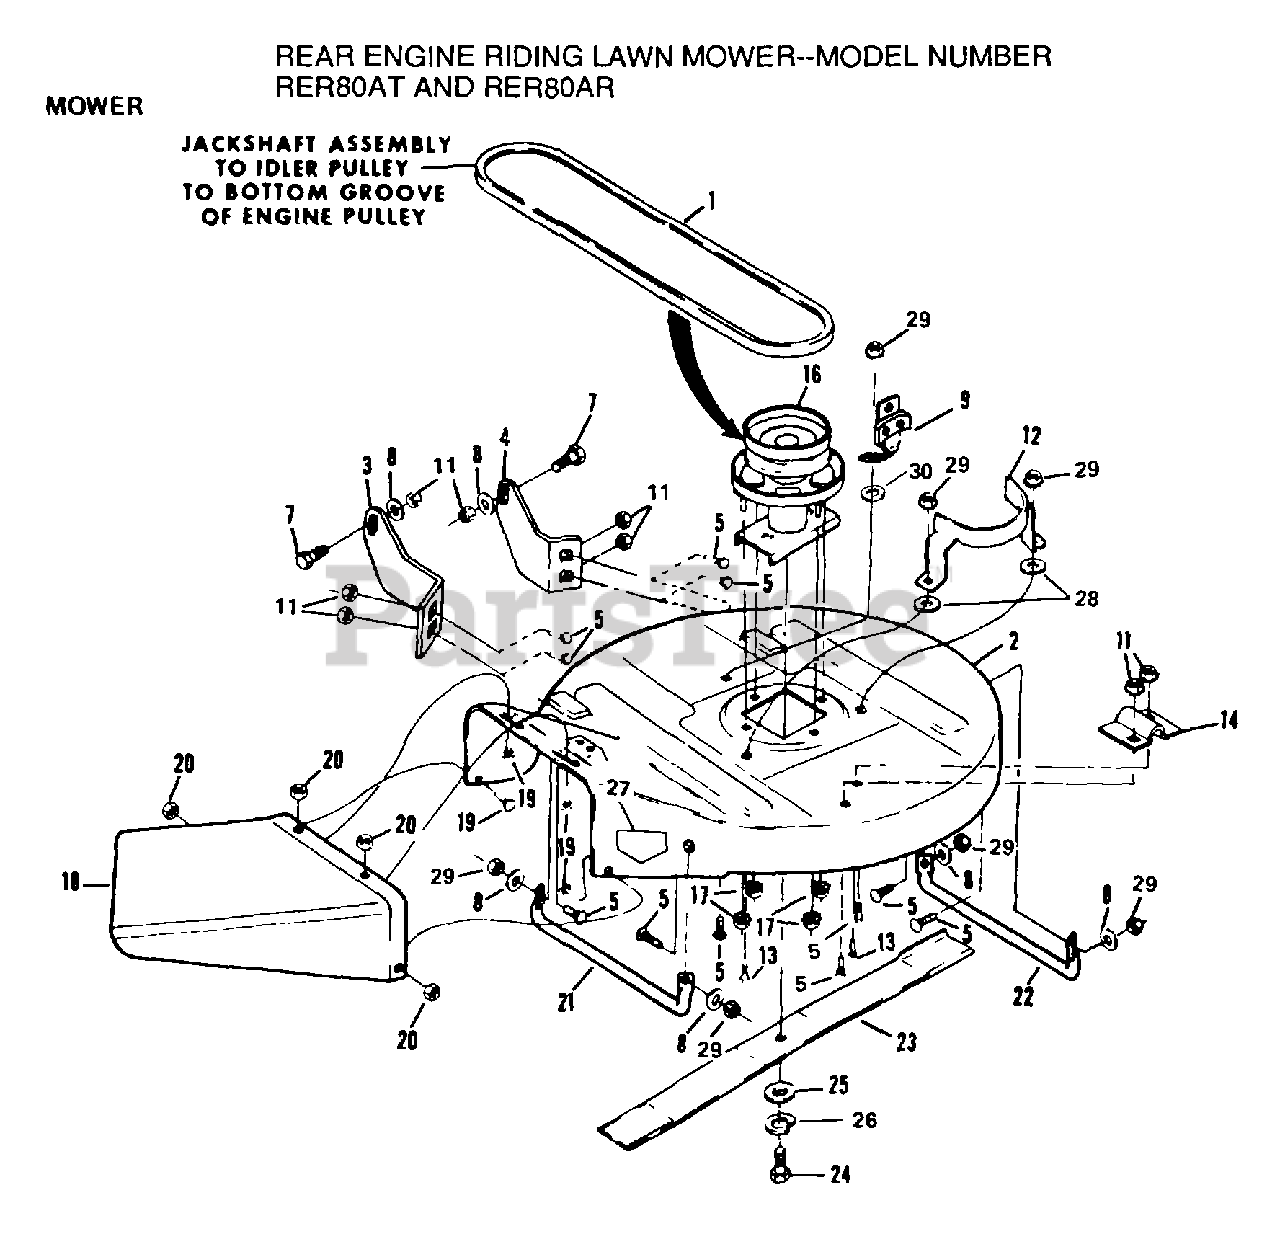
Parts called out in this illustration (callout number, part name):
1	V-BELT RER
2	HOUSING W/SILK SCREENING
3	HOUSING LIFTE T
4	HOUSING LIFTE T
7	SHOULDER BOLT T
8	WASHER M
12	BELT SNUBBER T
14	MOWER SUPPORT T
16	JACKSHAFT RER
18	DISCHARGE GUARD
26	LOCKWASHER
27	DECAL HYT
